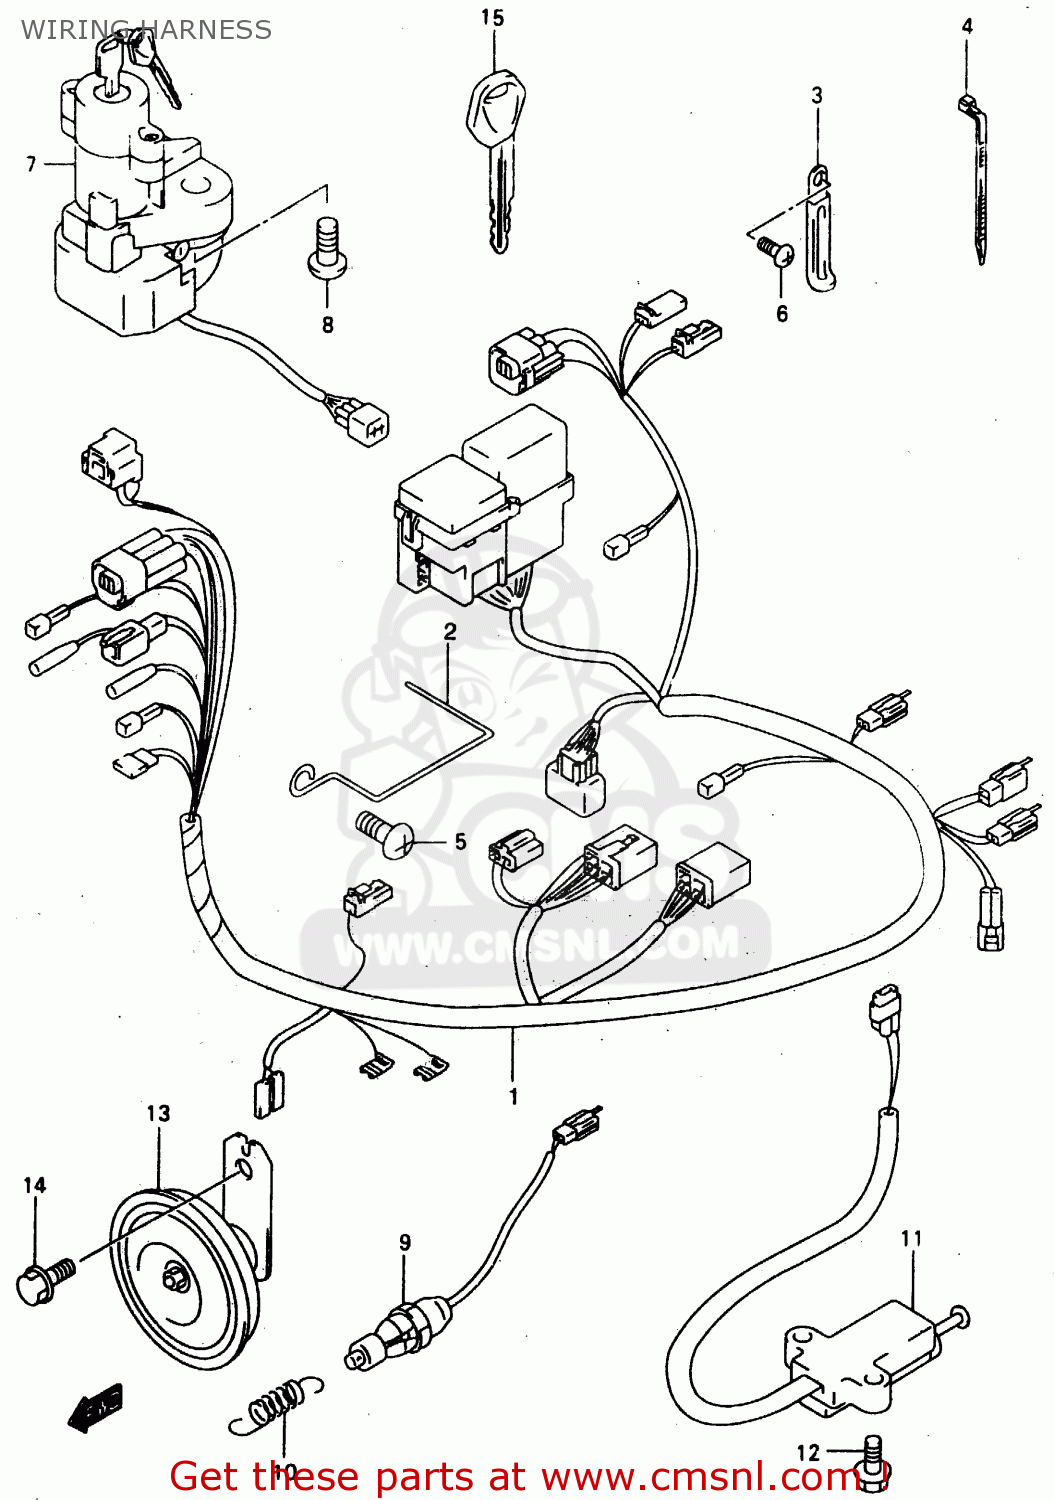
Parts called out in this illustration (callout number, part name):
1	HARNESS,WIRING
2	GUIDE,HARNESS
3	CLAMP(L:65)
4	CLAMP(L:125)
5	SCREW 6X12
6	SCREW
7	LOCK ASSY,STEERING
8	BOLT(8X20)
9	SWITCH ASSY,STOP LAMP
10	SPRING
11	SWITCH ASSY,SIDE STAND
12	BOLT
13	HORN ASSY
14	BOLT
15	KEY,BLANK
